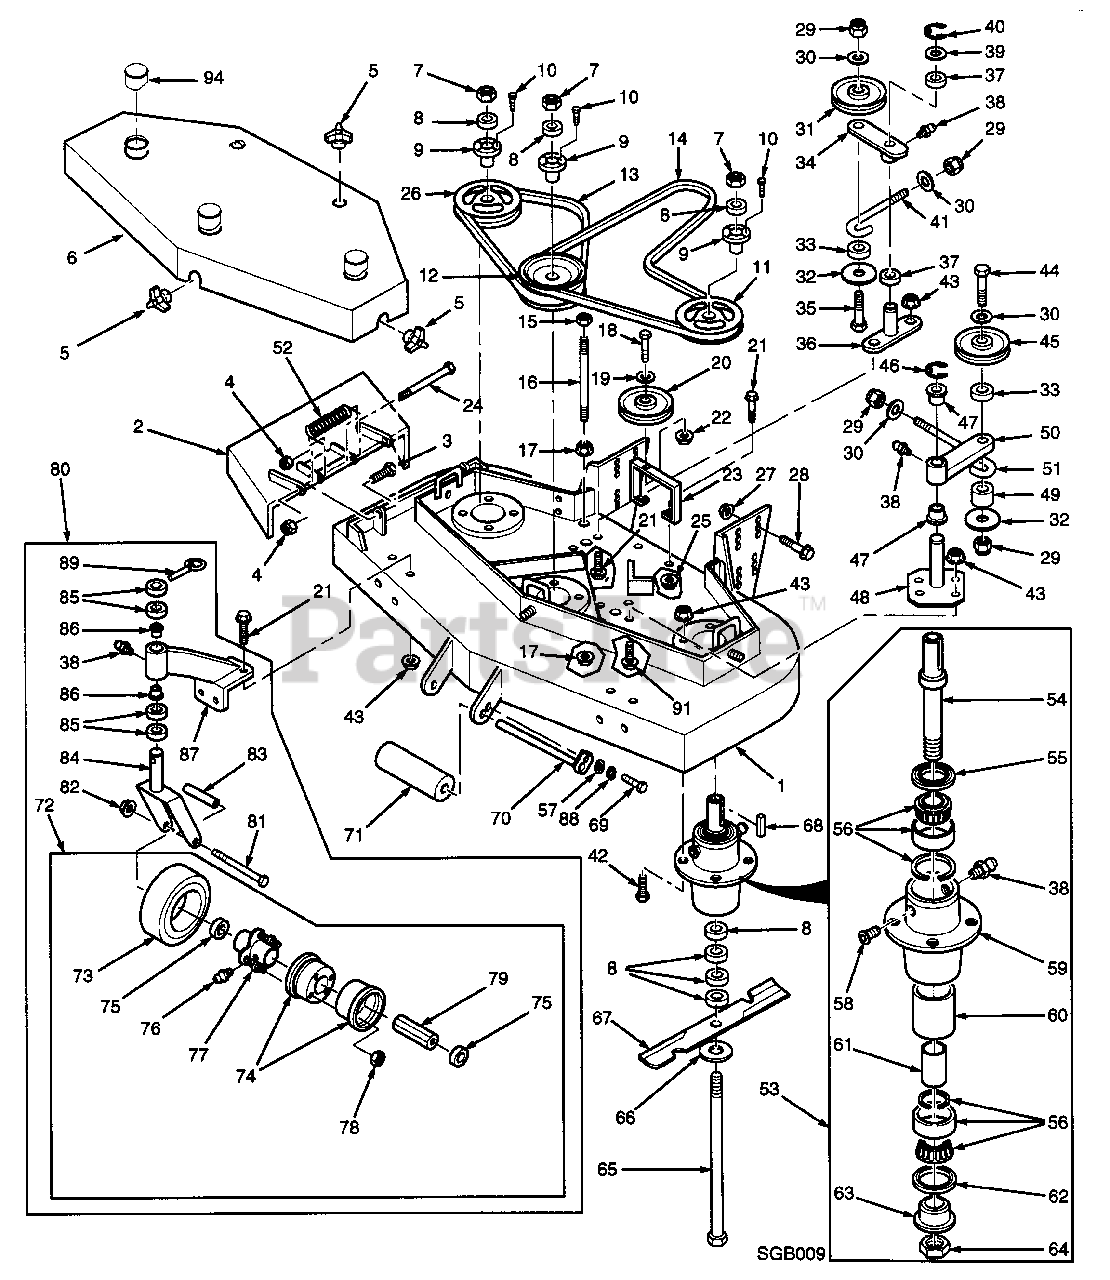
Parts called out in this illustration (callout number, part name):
1	CUTTER DECK(INCLUDES DECALS)
2	DISCHARGE CHUTE
3	BOLT, 5/16-18 X 1" HEX HEAD
4	NUT, 5/16-18 ELASTIC STOP
5	WING NUT, 3/8-16
6	BELT COVER(INCL. DECALS)
7	NUT, 5/8-11 HEX HEAD
8	SPACER, CUTTER BLADE
9	TAPERED HUB, 1.125 BORE
10	BOLT, 1/4-20 X 3/4 HEX HEAD
11	PULLEY, 5.75 O.D.
12	PULLEY, DOUBLE GROOVE, 5.75 O.D.
13	BELT, R.H. BLADE DRIVE
14	BELT, DECK DRIVE
15	LOCK NUT, 3/8-16 HEX HEAD
16	STUD, 3/8-16 X 6-3/4"
17	NUT, 3/8-16 SERR. FLANGE
24	BOLT, HEX HEAD 5/16-18 X 4-1/4"
26	PULLEY, 5.75
27	NUT, 1/2-13 SER. FLG. HEX HD.
28	CAPSCREW, 1/2-13 X 1-1/4 SER. FLG.
29	NUT, 3/8-16 ELASTIC STOP
30	FLATWASHER, 3/8(.391 X .938 X .105)
31	PULLEY
32	FLATWASHER, 3/8(.375 X 1.50 X .060)
33	SPACER
34	IDLER ARM(INCL. 37 & 38)
35	BOLT, 3/8-16 X 2-1/4"
36	IDLER PIVOT
37	BUSHING, BRONZE OILITE-3/4 ID
38	GREASE FITTING, STR. 1/4-28 SELF TAP.
39	FLATWASHER, 3/4(.776 X 1.25 X .059)
39	FLATWASHER, 3/4(.776 X 1.25 X .035)
40	RETAINING RING, .75 EXT 'E'
41	J-ROD IDLER PULLEY
42	BOLT, 5/16-18 X 1-1/4" HEX HEAD
43	NUT, 5/16-18 SER. FLANGE
44	BOLT, 3/8-16 X 3-1/2" HEX HEAD
45	PULLEY, DECK DRIVE IDLER
46	RETAINING RING, 1-1/8 EXT 'E'
47	BUSHING, BRONZE OILITE- 1-1/8 ID
48	IDLER PIVOT SUPPORT
49	SPACER
50	IDLER ARM(INCL. 38 & 47)
51	J-ROD, DRIVE IDLER
52	SPRING, CHUTE RETURN
53	SPINDLE ASSEMBLY
54	SHAFT, CUTTER SPINDLE
55	SEAL, 2.00 O.D. X 1.50 BORE
56	BEARING ASSEMBLY
57	FLAT WASHER, 5/16(.375 X .875 X .083)
58	RELIEF FITTING, CUTTER SPINDLE
59	SPINDLE HOUSING
60	SPACER, OUTSIDE
61	SPACER, INSIDE
62	SEAL, 2.00 O.D. X 1-5/8 BORE
63	SPINDLE BUSHING BOTTOM
64	NUT, 1-1/16-18 UNEF-2B
65	BOLT, 5/8-11 X 9-1/2"
66	FLATWASHER, 5/8(.688 X 1.75 X .134)
67	CUTTER BLADE, 18" STANDARD
67	CUTTER BLADE, 18" HI-LIFT
68	KEY, 1/4 X 1/4 X 2"
69	BOLT, 5/16-18 X 3/4" HEX HEAD
70	SHAFT, ROLLER
71	GUIDE, ROLLER
72	WHEEL ASSY., CASTER
73	TIRE ONLY, CASTER WHEEL
73	INNER TUBE ONLY, CASTER WHEEL
74	RIM PAIR, CASTER WHEEL
75	RETAINER, CASTER WHEEL
76	GREASE FITTING, 45 DEG. 1/4-28
77	HUB ASSY. W/BOLTS, CASTER WHEEL
78	TAPERED HEX NUT, 5/16-18
79	ROLLER BEARING, CASTER WHEEL
80	CASTER WHEEL ASSEMBLY
81	BOLT, 1/2-13 X 5-1/2" HEX HEAD
82	NUT, 1/2-13 ELASTIC STOP
83	SLEEVE, CASTER WHEEL BEARING
84	CASTER YOKE
85	SPACER, CASTER YOKE 1/2"
86	BUSHING, 7/8 X 1" FLANGED
87	SUPPORT ASSEMBLY(INCL. 38-86)
88	LOCK WASHER, 5/16
89	QUICK PIN
91	CAPSCREW, 5/16-18 X .75 SER. FLG.
